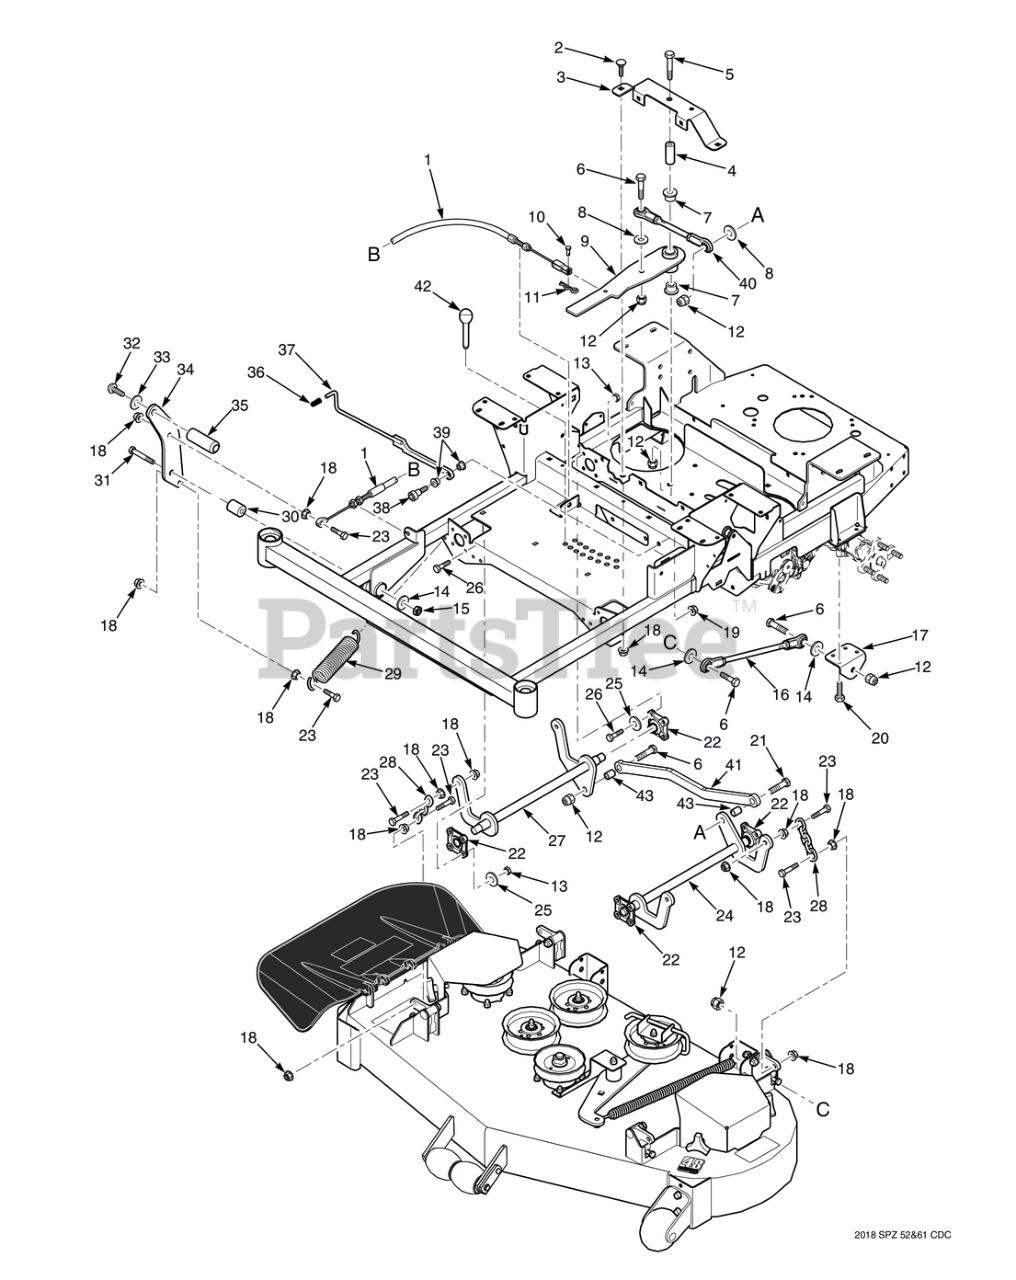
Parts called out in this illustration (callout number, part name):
1	Cable, Deck Lift
2	Bolt, Carriage 3/8-16 x 3/4"
3	Support, Idler Arm
4	Spacer, Deck Lift Pivot
5	Bolt, Hex Head, 1/2-13 x 3-1/4"
6	Hex Head Bolt, 1/2-13 x 2"
7	Bearing, Plastic
8	Flatwasher, 1/2 - .531 x 1.062 x .095
9	DECKLIFT BELLCRANK ASSY, SFZ
10	Clevis Pin, 5/16 x 3/4"
11	COTTER PIN, HAIR - 0.94 X 1.62
12	HEX LOCKNUT, ELASTIC STOP, 1/2-13
13	HEX NUT, ELASTIC STOP LOCK, 5/16-18
14	Flat Washer, 1/2 (.562 x 1.375 x .109)
15	HEX NUT, ELASTIC STOP LOCK, 3/8-16
16	Linkage, Push Arm
17	Bracket, Push Arm Link
18	NUT, 3/8-16 SERRATED FLANGE HEX HEAD
19	HEX NUT, ELASTIC STOP LOCK, 3/8-16
20	Bolt, Hex Head 5/16-18 x 3.00"
21	Bolt, Hex Head 1/2-13 x 3"
22	Bearing, Deck Lift - 48V & 52V
23	Bolt, Hex Head, 3/8-16 x 1-1/2"
24	Weldment, Deck Lift LH
25	Flatwasher, 1/4" (.312 x .750 x .065")
26	Bolt, Heax Head 5/16-18 x 1" (48V / 52V)
27	Weldment, Deck Lift RH
28	Chain, Deck Lift
29	Spring, Deck Lift
30	Spacer, Deck Lift Pivot
31	Bolt, Hex Head 1/2-13 x 3"
32	Bolt, Head Socket 5/8-11 x 1-1/2"
33	Lockwasher, 5/8" Spring
34	Pedal, Foot Bracket
35	Foot Pedal, Height Adjustment
36	Grip, Deck Latch
37	Weldment, Deck Latch
38	Bolt, Shoulder 1/2 x 1/2"
39	Bearing
40	Linkage Assembly, Deck Lift
41	Mounting Bracket, Fuel Tank Front
42	Pin, Height Adjuster
43	Sleeve
